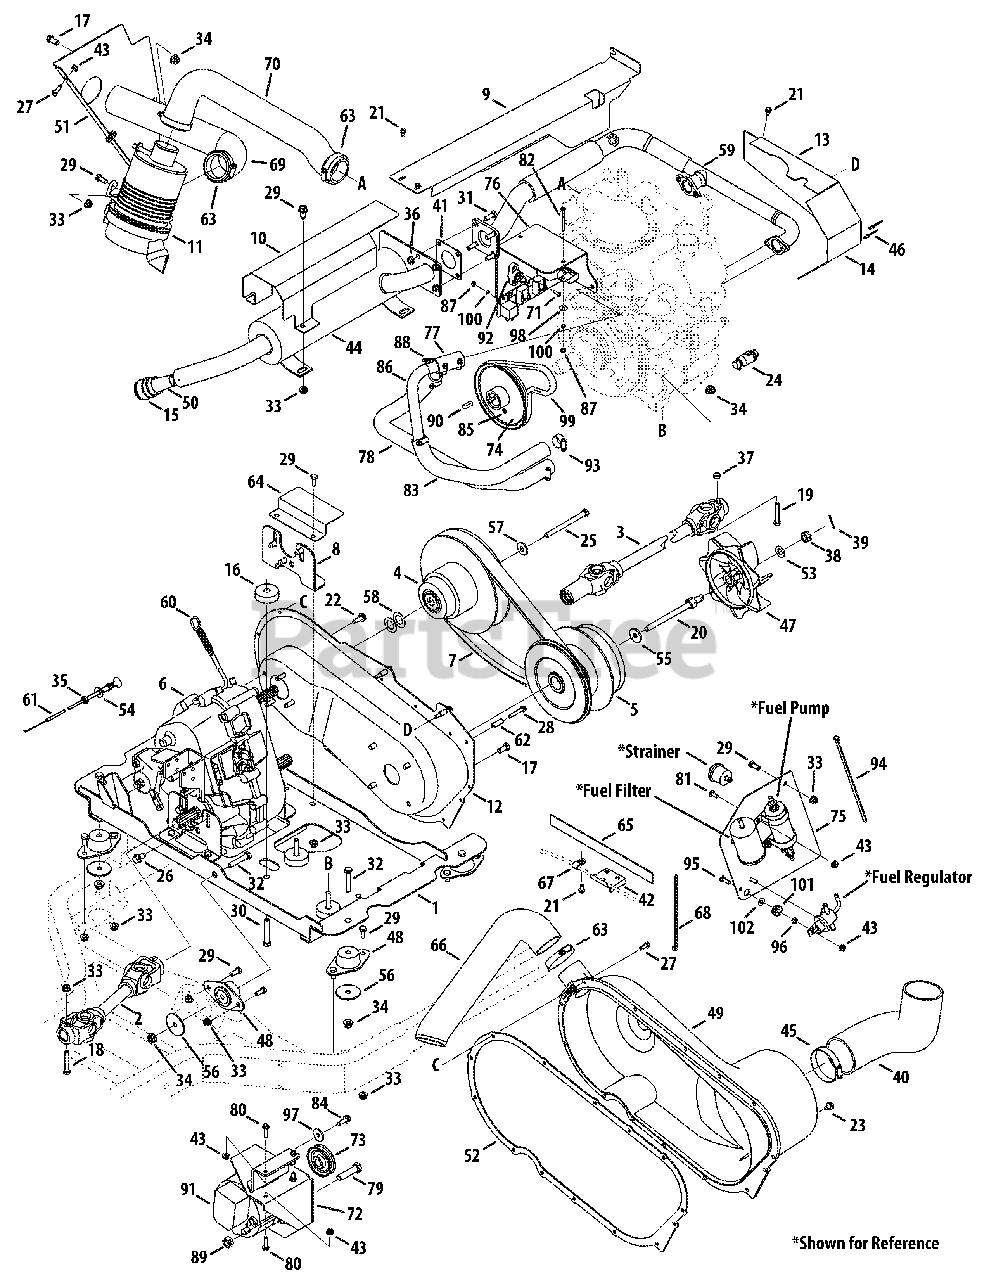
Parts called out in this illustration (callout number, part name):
1	Tray Assembly, Engine, Kohler
2	Shaft Assembly, Rr/prop
3	Shaft Assembly, Frt/prop, Hilliard
4	Clutch Assembly, Cvt, Driven
5	Clutch Assembly, Cvt, Driver, Cvr
6	Case Assembly, Transfer
7	Belt, Cvt, 4x4
8	Bracket, Trans, Mount
9	Cover, Heat, Shield
10	Exhaust, Shield, Heat
11	Filter Assembly, Air Cleaner
12	Cover, Back, Kohler
13	Cover, Eng, Kohler
14	Cover, Engine, Rr, Kohler
16	Spacer, Engine, Kohl
17	Hex Head Screw, 3/8-16, .75
18	Hex Head Screw, 5/16-18, 2.00
19	Hex Head Screw, 5/16-18, 1.875
20	Hex Head Screw, 7/16-20, 5.00
21	Screw, Tt, 1/4-20, 0.500
22	Screw, Tt, 5/16-18, .875
23	Screw, B, 5/16-12, 0.500
25	Hex Head Screw, 3/8-24, 3.50
26	Screw, Tt, 3/8-16, 0.750
27	Screw, Tt, 1/4-20, 0.750
28	Screw, Tt, 1/4-20, 1.625
29	Hex Head Screw, 5/16-18, .75
30	Hex Head Screw, 3/8-16, 2.25
31	Hex Head Screw, 5/16-18, .875
32	Hex Head Screw, 3/8-16, 2.00
33	Nut, Flange Lock, 5/16-18, Nylon
34	Nut, Flange Lock, 3/8-16, Nylon
35	Nut, Jam, 3/8-24
36	Nut, Flange Lock, 5/16-18
37	Nut, Hex Lock, 5/16-18, Ctrlk
38	Nut, Hex, 1/2-20, Gr5, Slot
39	Pin, Cotter, 3/32, 1.0
40	Tube, Cvt, Intake
41	Gasket, Engine
42	Bracket, Cable Shield
43	Nut, Flange Lock, 1/4-20
45	Clamp, Hose, Adj.
46	Rivet, Pop, .125 Od, #42
47	Impeller, Blower
48	Compression Mount, Eng, Head
49	Cover, Cvt
50	Spark Arrester Screen
51	Plate, Baffle
52	Seal, CVT, Cvr
53	Washer, Flat, .510 x 1.00 x .060
54	Washer, Flat, .406 x .875 x .059
55	Washer, Flat, .450 x 1.250 x .164
56	Washer, Flat, .38 x 2.00 x .12
57	Washer, Bell, .396 x 1.140 x .095
58	Washer, Flat, .793 x 1.368 x .025
59	Pipe, Exhaust, Kohl, EFI
60	Cable, Throttle Control, Kohler
61	Cable, Choke Control, Kohler
62	Spacer, .260 Id x .375od x 1.0l
63	Clamp, Hose
64	Shield, Harness
65	Heat Shield Sleeve
66	Hose, CVT, Exhaust
67	Clamp, Hose
68	Tie, Cable
69	Hose, Air, Inlet
70	Hose, Air, Intake
71	Screw
72	Support, Asm, Alternator, Kohler
73	Pulley, 2.65 OD x 3L
74	Pulley, 6.00 OD x 1.125
75	Bracket, Fuel System, Kohler EFI
76	Bracket, Electrical, Kohler EFI
77	Hose, Rdtr, Top Rear
78	Hose, Rdtr, Lower Rear
79	Hex Head Screw, 1/2-13 x 2.00
80	Screw, tt, 1/4-20 x 1.00
81	Screw, Machine, 1/4-20 x .625
82	Screw, Machine, #10-32 x 2.00
83	Hose, Radiator
84	Screw, 5/16-18 x .875
85	Screw, 1/4-20 x 3/8
86	Tube, Rdtr
87	Nut, Hex, #10-32
88	Fitting, Petcock
89	Nut, Hex Lock, 1/2-13
90	Square key, 1/4 x .75lg
91	Alternator, Aux, 65 Amp
92	Electric Power Distribution Post
93	Clamp, Hose, Adj
94	Tie, Cable
95	Screw, Machine, 1/4-20 x .750
96	Nut, Hex, 1/4-20
97	Washer, Flat, .344 x 1.125 x .12
98	Washer, Flat, .194 x .62 x .063
99	Belt, V-Type
100	Washer, Lock
101	Rubber Grommet
102	Washer, Flat, .25 x .630 x .0515
